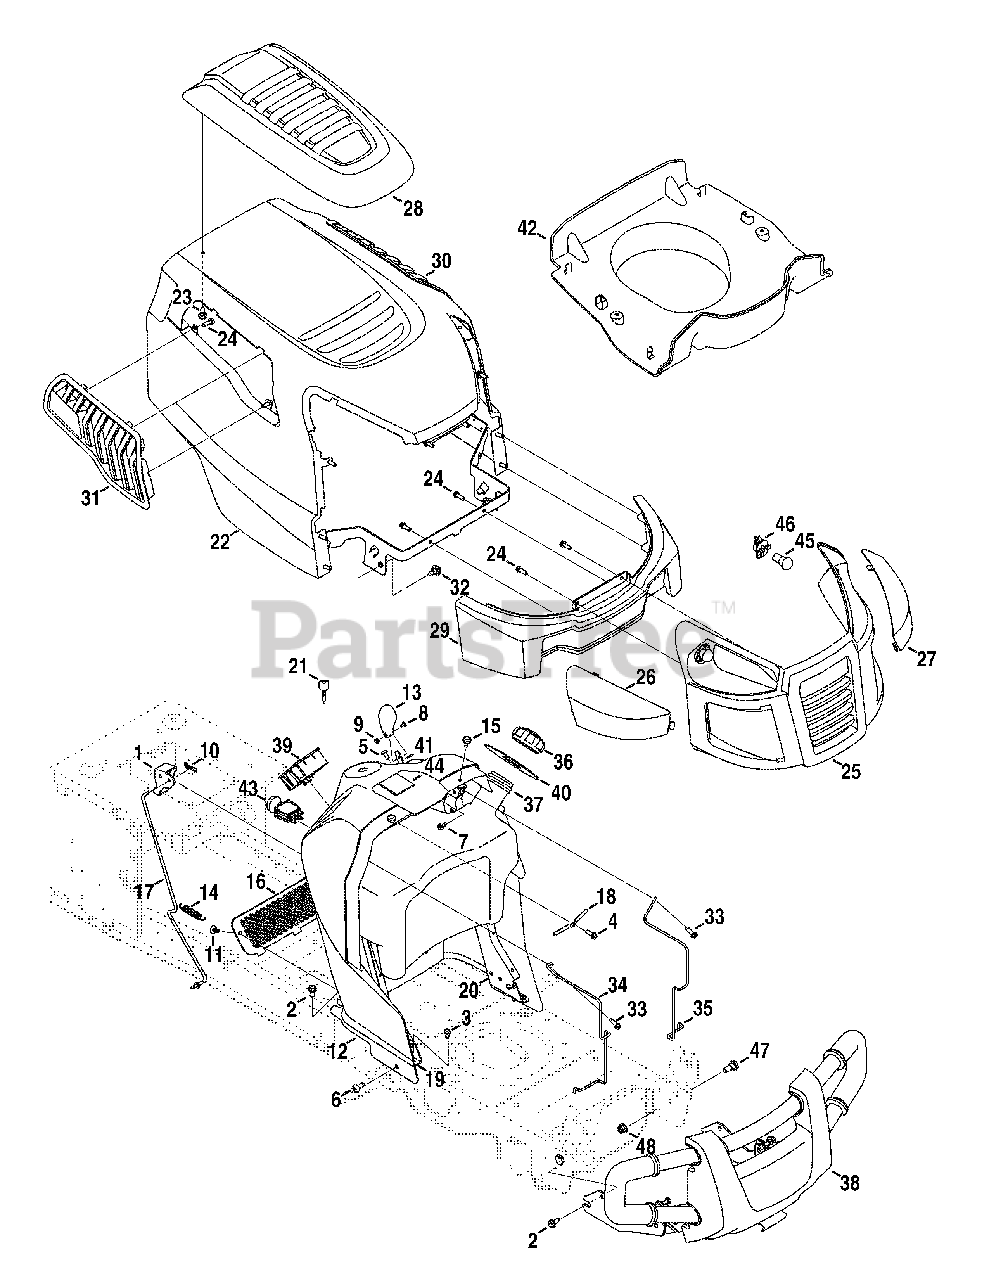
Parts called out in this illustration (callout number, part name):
1	Dash Lever
2	Taptite Screw, Lock Washer, 5/16-18:.750
3	Taptite Screw, Lock Washer, 1/4-20:0.500
4	Hi-Lo Screw, Lock Washer, 1/4-15:0.750
5	Screw, 1/4-14:0.625
6	Taptite Screw, 5/16-18:0.750
7	Taptite Screw, 1/4-20 x .625
8	Machine Screw, #8-32:0.375
9	Hex Nut, #8-32:GRA
10	Bow-tie Cotter Pin
11	Ratchet Clip:.250 DIA
13	Control Knob
14	Extension Spring, .500 DIA x 2.733 LG
15	Bumper
16	Accessory Net
17	Control Rod Latch
18	Lever Rod
19	RH Dash Support Plate
20	LH Dash Support Plate
21	Key (Set of 2)
22	Hood Assembly
23	Hi-lo Screw, Lock Washer, 1/4-15:0.50
24	Screw, Lock Washer, 1/4 DIA:.750
26	RH Lens
27	LH Lens
28	Hood Scoop
29	Lower Grill
30	LH Hood Scoop
31	RH Hood Scoop
32	Shoulder Screw, .43 x .29:TT:5/16-18
33	Taptite Screw, 1/4-20:0.750
34	RH Tank Support Rod
35	LH Tank Support Rod
36	Fuel Cap
37	Fuel Tank, 2.75 Gallons
38	Guard Assembly
39	Key Switch Module
40	Fuel Tank Gasket
41	Throttle Control
42	P-Style Plen
43	PTO Switch
44	Hour Meter
45	Miniature Lamp, 12V
46	Lamp Socket
47	Shoulder Bolt, .496 x .336:3/8-16
48	Flangelock Nut, 3/8-16
